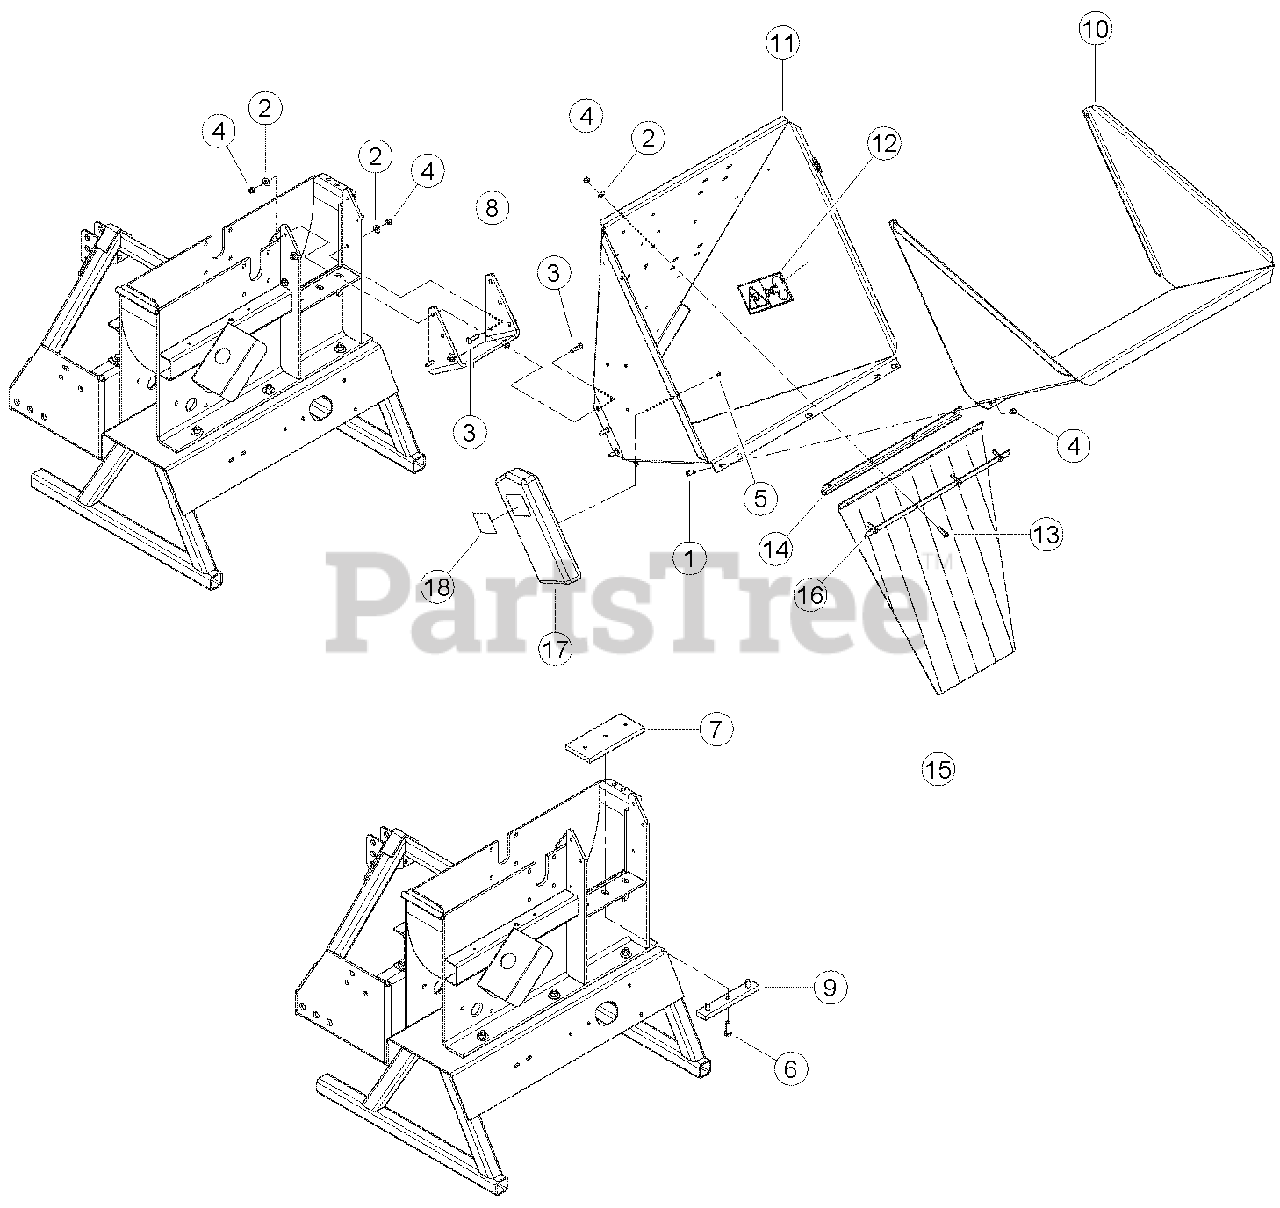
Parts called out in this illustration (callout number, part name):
1	BOLT, 3/8 X 1 HEX HD GR5 ZP
2	WASHER, 3/8 FLAT ZP
3	BOLT, 3/8 X 1-1/2 CRG GR5 NC ZP
4	NUT, 3/8 NE NYLOCK ZP
5	RIVET, 1/4 X 1/2 DOME HD BLIND SS
6	BOLT, 1/2 X 1-1/2 HEX HD GR8 NC ZP
7	PLATE, CHIPPER BOTTOM
8	BASE, CHIPPER CHUTE
9	SPACER, CHIPPER ANVIL
10	WELDMENT, CHUTE EXTENTION TRAY
11	ASSEMBLY, CHIPPER CHUTE, SERVICE PART
12	DECAL, BLADE DANGER ISO
13	BOLT, 3/8 X 1-1/4 HEX HD GR5 ZP
14	ANGLE, FLAP ANCHOR
15	FLAP, CHIPPER CHUTE
16	STRIP, FLAP RETAINER
17	ASSEMBLY, MANUAL CONTAINER, SERVICE PART
18	DECAL, MUTILINGUAL MANUAL
